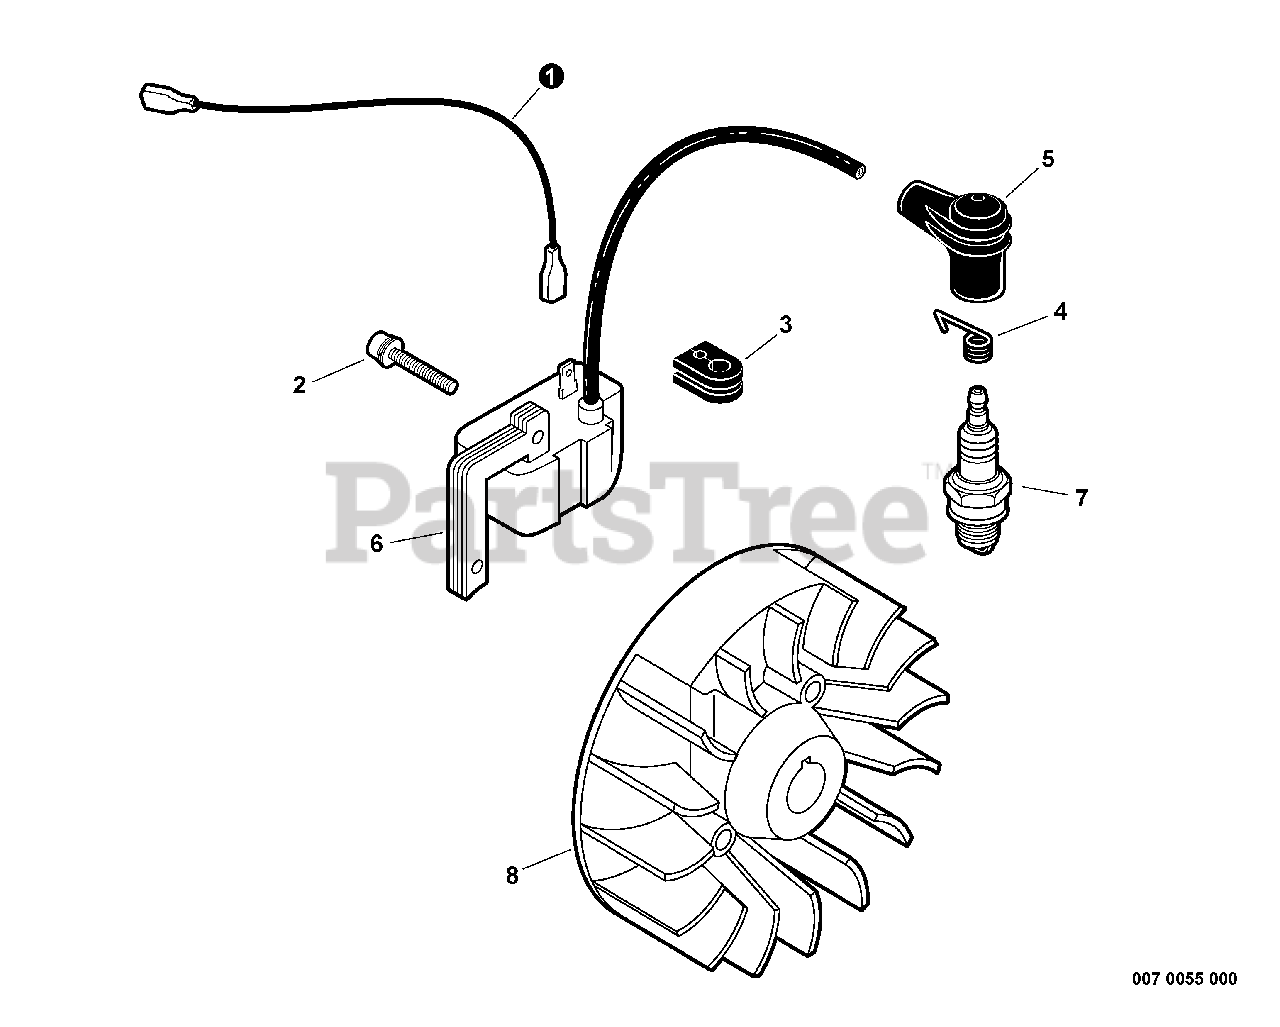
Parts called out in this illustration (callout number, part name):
1	LEAD - IGNITION
2	SCREW - 4X22
4	TERMINAL, SPARK PLUG CAP
5	CAP, SPARK PLUG
6	COIL, IGNITION
7	SPARK PLUG -- BPM-7A
8	FLYWHEEL
